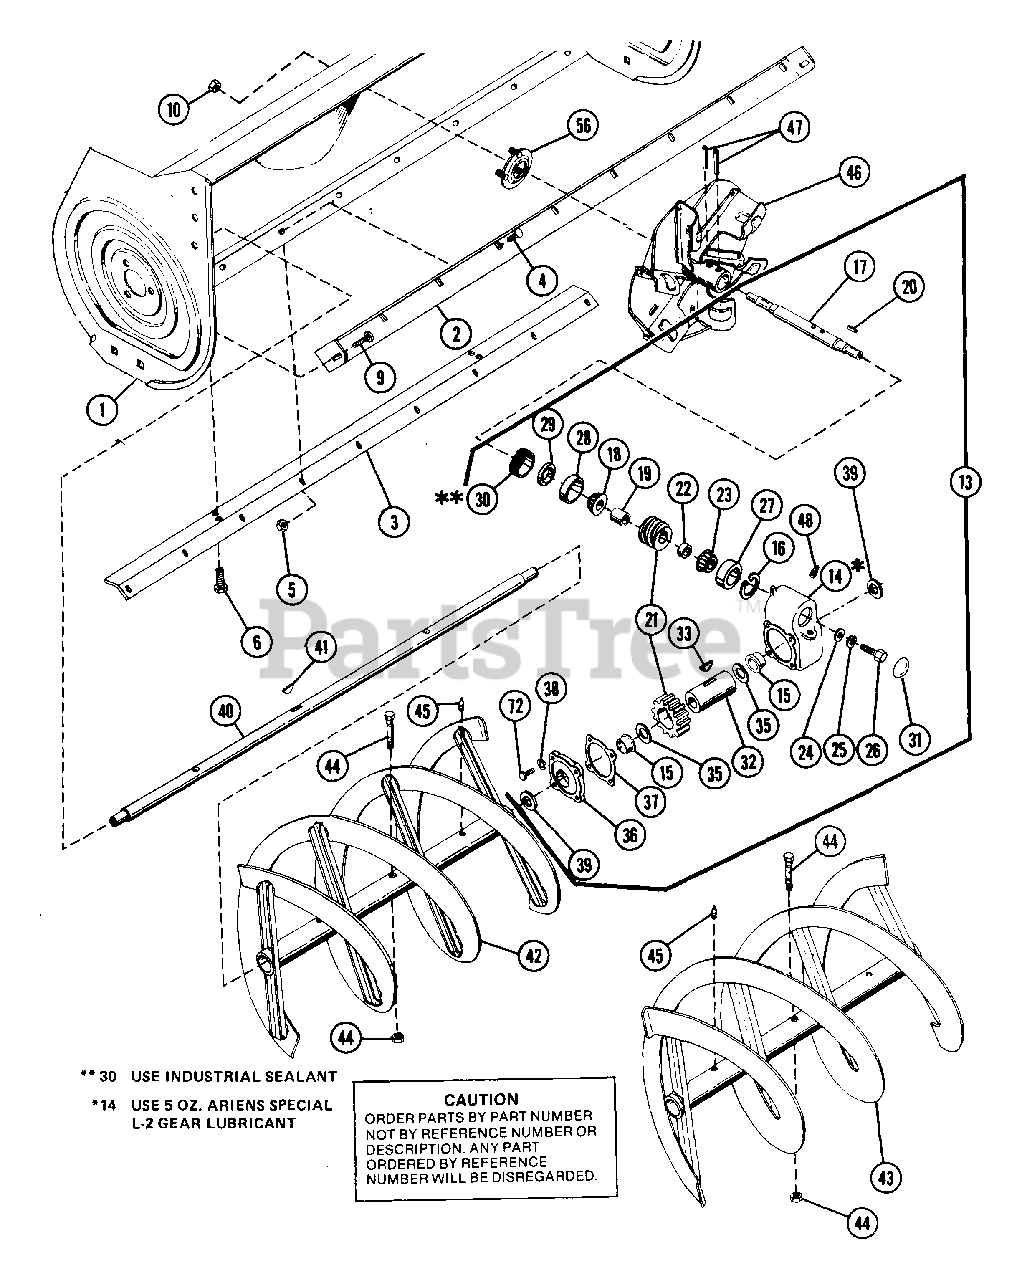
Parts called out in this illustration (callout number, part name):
1	BLOWER HOUSING ASSEMBLY
2	SCRAPER BLADE
3	SCRAPER BLADE BRACE
4	BLT-RDHDSQNK .31-18X.75 GR5 PL
5	NUT-LK .312-18 GR A PL
6	BLT-HEX .38-16X.75 PL GR5
9	BLT-RDHDSQSHNK .38-16X1.00 PL
10	NUT-LK .312-18 GR A PL
13	GEAR CASE - CAST IRON
14	GEAR CASE - CAST IRON
15	BSHG-FLG .683X1.87X1.68X2.250
16	RG-RTNG INT 1.781 HSG X.062
17	WORM SHAFT
18	BRG-CONE 1.0X.58
19	BEARING SPACER 1.032X1.25X1.78
20	KEY-SQ .188X1.0X.188 SAE 8630
21	WORM & GEAR SERVICE ASSEMBLY
22	BSHG, SPCR .755X1.12X.50 PM
23	BRG-CONE .750X.61
24	WSHR-FL-STL .328X1.0X.094
25	WSHR-LK .312X.097 PL HVY
26	BLT-HEX .31-18X.75 PL GR2
27	BRG-CUP 1.781X.475
28	BRG-CUP1.980X.420
29	SEAL 1.125X1.375X.125
30	ADJUSTMENT PLUG
31	DUST CAP
32	GEAR CASE SHAFT
33	KEY-FTHR .25X.875X.312
35	WSHR-FL-STL 1.625X2.500X.012
36	GEAR CASE COVER
38	WSHR-LK-EXT. 250 ID
39	SEAL 1.625X2.125X.250
40	RAKE SHAFT
41	KEY-WDRF .25X.875X.375 SAE A
42	RAKE, RIGHT-48(1.12ID X 15.75)
43	RAKE, LEFT-48"(1.12ID X 15.75)
44	SHEAR BOLT & NUT ASSEMBLY
45	SPIN DRIVE ZERK FITTING
47	PIN-ROLL .313X1.75
48	PIPE PLUG
56	BEARING FLANGE
72	BLT-HEX .25-20X.75 PL GR2
